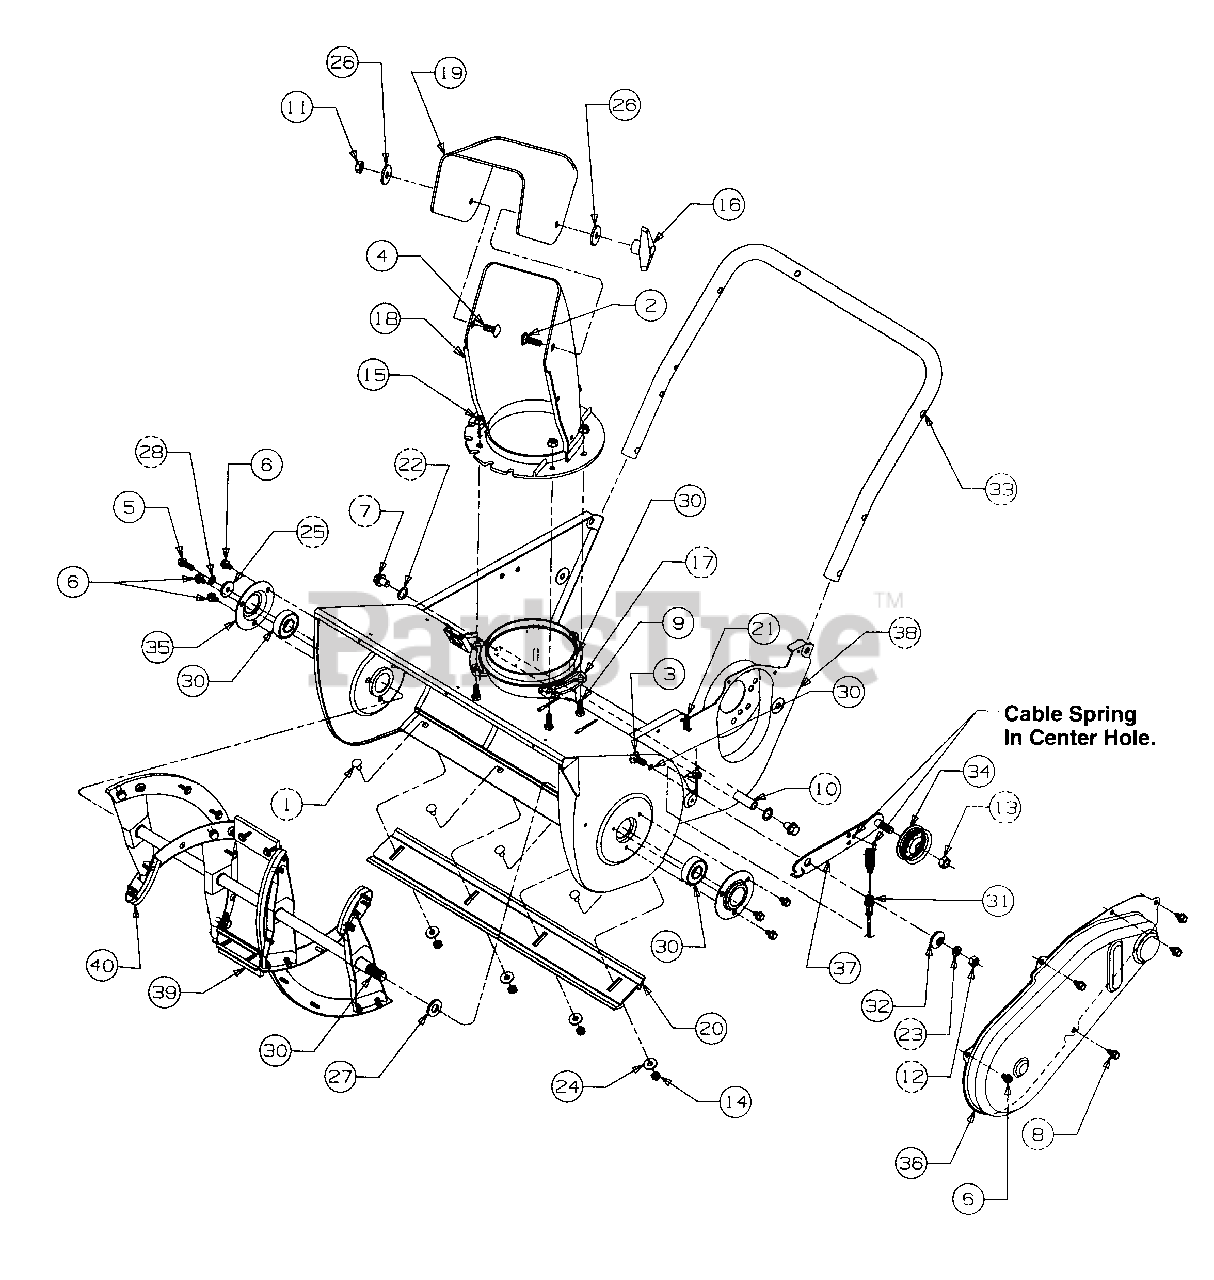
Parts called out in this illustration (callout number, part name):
1	Bolt - Carriage
2	Bolt - Carriage
3	Screw - Pan Head
4	Bolt - Carriage
5	Screw - Hex Washer
6	Screw - Hex Washer
7	Screw - Hex Washer
8	Screw - Hex Washer
9	Screw - Hex Cap
11	Nut - Hex Center Lock
12	Nut - Hex
13	Nut - Hex Lock
14	Nut - Hex Jam
15	Nut - Hex Lock Flanged
17	Keeper - Chute
18	Chute - Lower
19	Chute - Upper
20	Shave Plate
21	Spring - Extension
22	Washer - Flat
23	Washer - Lock
24	Washer - Flat
25	Washer - Flat
27	Washer - Flat
28	Washer - Lock
30	Ball Bearing
31	Cable - Clutch
32	Spacer - Shoulder
37	Bracket - Idler/Brake
40	Auger Rubber Replacement
